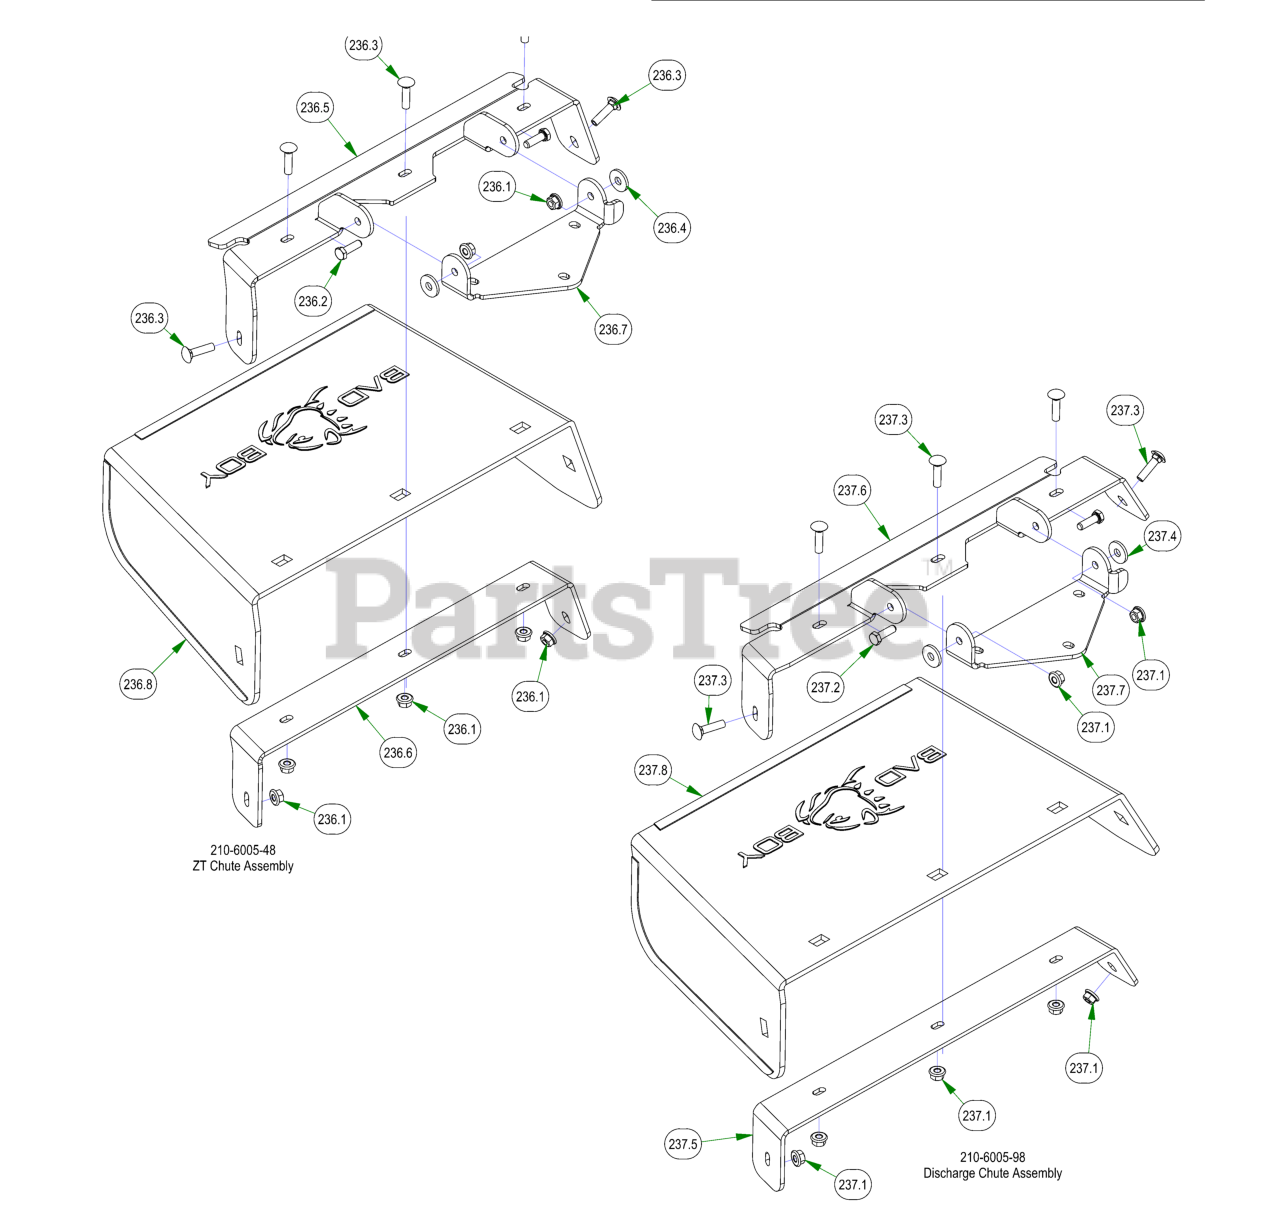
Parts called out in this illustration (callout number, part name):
59	5/16-18 X 1-1/4 CARRIAGE BOLT ZINC
108	2023 4" & 5" Stripping Kit Plate
202	2023 ZT Stripping Kit Rubber
236	ZT Chute Assembly
236.1	5/16-18 NYLON INSERT FLANGE LOCKNUT ZINC
236.2	5/16-18 X 1 HEX CAP SCREW (GR.5) ZINC
236.3	5/16-18 X 1-1/4 CARRIAGE BOLT ZINC
236.4	.360 ID X .983 OD X .120 THICK FLAT WASHER NYLON
236.5	Discharge Upper Chute Bracket
236.6	Discharge Lower Chute Bracket
236.7	Discharge Chute Hanger (deck mounted)
236.8	Rubber Discharge Chute
237	Discharge Chute Assembly
237.1	5/16-18 NYLON INSERT FLANGE LOCKNUT ZINC
237.2	5/16-18 X 1 HEX CAP SCREW (GR.5) ZINC
237.3	5/16-18 X 1-1/4 CARRIAGE BOLT ZINC
237.4	.360 ID X .983 OD X .120 THICK FLAT WASHER NYLON
237.5	60" Discharge Lower Bracket
237.6	60" Discharge Chute Upper Hanger
237.7	Discharge Chute Hanger (deck mounted)
237.8	Rubber Discharge Chute
